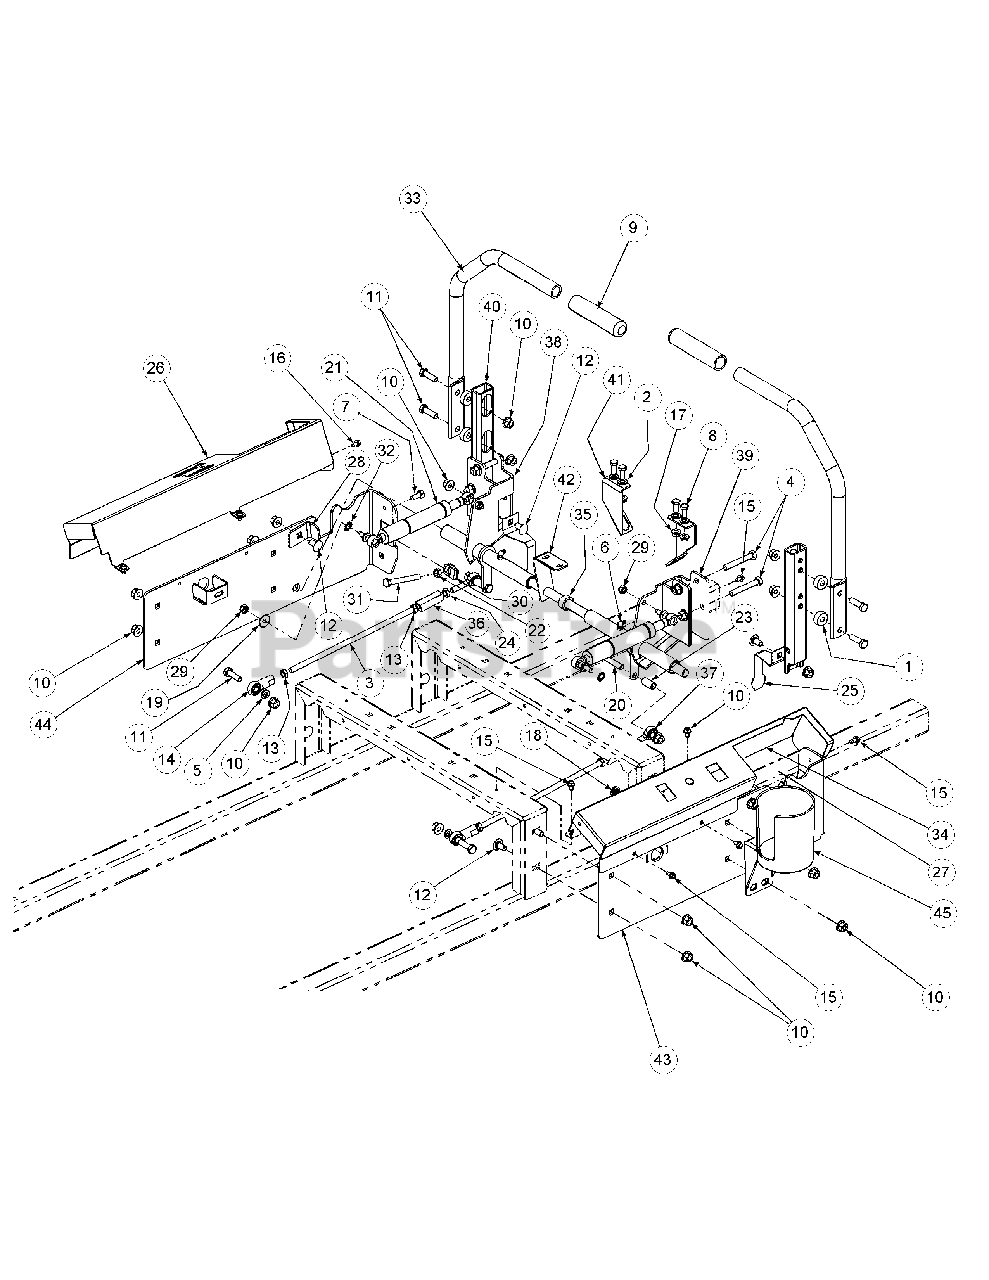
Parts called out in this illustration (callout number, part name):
1	Spacer, .406 ID x 1.00 OD x .38
2	Flat Washer, 5/16
3	Rod Connector, 3/8-24 x 11.00 Long
4	Hex Cap Screw, 3/8-16, 2.5
5	Lock Washer, 3/8
6	Grease Fitting, 90°, 1/4-28
7	HHCS, 5/16-18 x 1.0
8	Hex, Cap Screw, 5/16-18 x 3/4
10	Hex Nut, 3/8-16, Lock Flange
11	Hex Cap Screw, 3/8-16, 1.25
12	Carriage Bolt, 3/8-16 x .75
13	Hex Jam Nut, 3/8-24
14	B/Joint, 3/8-24, Right Hand Female
15	Screw, TT, 1/4-20, 0.5, Hex Index Washer
16	Screw, TT, 1/4-20, 0.75, Hex Index Washer
17	Nut, Lock, HexFlange, 5/16-18
18	Carriage Bolt, 3/8-16 x 1
19	Belle Washer, .325 x .930 x .045
20	Hex Cap Screw, 3/8-16 x 2.25
21	Cylinder Return to Neutral
22	Nut, 3/8-16, Jam
23	Spacer, .375 x .50 x 1.02
24	Nut, 3/8-24, Jam, LH Third
25	Lever, Safety Switch
26	Control Panel, LH
29	Nut, Hex, Center Lock, M8 x 1.2
30	U-Nut, 3/8-16 x .75
31	HHCS, 3/8-16, 3.00
32	External Lock Washer
33	Lapbar Handle, One Position
34	Control Panel, RH
35	Shaft Collar, .625 ID, 1.00 OD, .438 LG
36	Turnbuckle
37	B/Joint, 3/8-24, Left Hand Female
38	Hub Assy, Control LH Bearing
39	Hub Assy, Control RH Bearing
40	Mounting Handle
41	Switch Mounting Bracket, Lapbar
42	Shaft Control Brake Steering
43	Side Panel, Control, Right
44	Side Panel, Control, Left
45	Cup Holder Assembly
